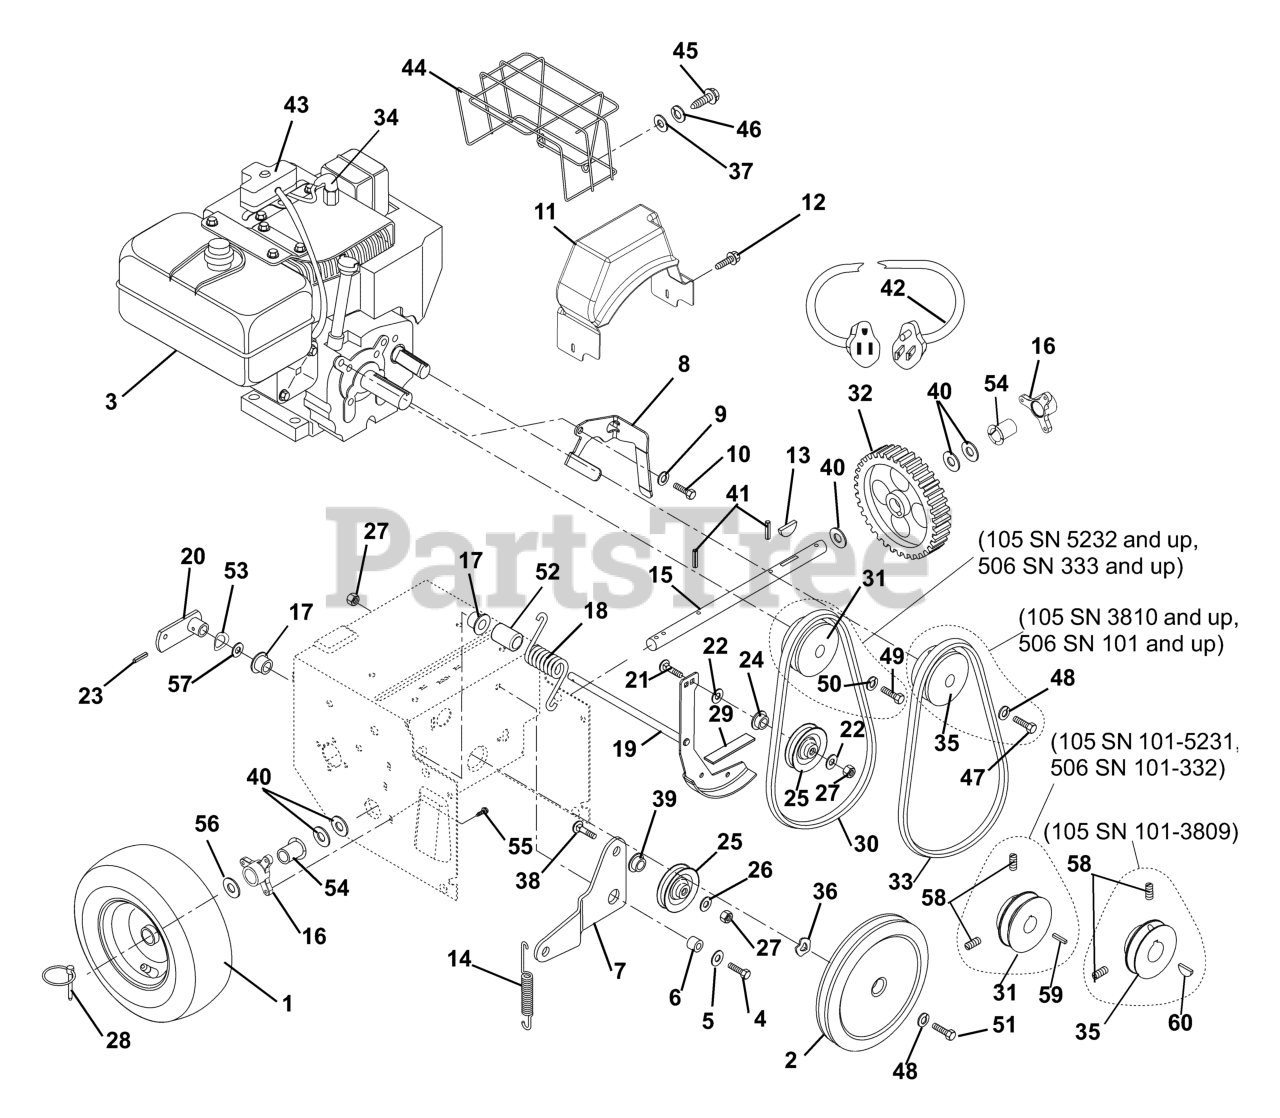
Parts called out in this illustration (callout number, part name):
1	WHEEL 5.00 X 6.00
2	PULLEY, 3L W/HUB, .625 X 6.5
3	ENGINE, 8.5HP TEC LHSA318 120V
4	@BLT-HEX .31-18X.75 GR5 YWZC
5	@WSHR-FL-STL.38X.875X.083 YWZC
6	SPACER BUSHING .5 X .32 X .163
7	IDLER ARM
8	BELT FINGER
9	WSHR-LK .312X.097 HVY YWZC
10	BLT-HEX .31-24X.75 YWZC GR5
11	COVER, BELT, HYBRID
12	@SCR-TAP .25-20X.37 HWH YWZ TR
13	KEY-WDRF .25X.750X.313 SAE91
14	SG-TENS .047X.44X3.37 WLD 1.47
15	AXLE SHAFT, 932 DELUXE (8526)
16	BUSHING, RAKE SHAFT .75"
17	BSHG-FLG .500X.625X.500X.750
18	SG-TORS
19	BRAKE ARM W/PAD
20	LEVER, CLUTCH
21	@BLT-RDHDSQNK .31-18X1.25 G5YZ
22	@WSHR-FL-STL.38X.875X.083 YWZC
23	PIN-ROLL .156X.88
24	SPCR, BRG .315X.50X.688X.281
25	IDLER
26	@WSHR-FL-STL.38X.875X.083 YWZC
27	@NUT-LK-CTR .31-18 YWZC
28	PIN-LOK .31X1.75
30	V-BELT, HA-RAW EDGE
31	SHEAVE, ENGINE LHSA318
32	SPUR GEAR, FELLOWS 35T .750 ID
33	V-BELT, 3L-RAW EDGE
34	PLUG, SPARK
35	SHEAVE, CAMSHAFT LHSA318
36	WSHR-WAVE .69X.84X.011
37	@WSHR-FL-STL.219X.50X.049 YWZC
38	BLT-RDHDSQNK .31-18X1.0 SHTYZ
39	BSHG, FLG .325X.499X.26X.88
40	WSHR-FL-STL.754X1.125X.062YWZC
41	PIN-ROLL .156X1.00
42	CORD, ELECTRIC START CORD 120V
43	120 V STARTER KIT- 8 TO 11.5HP
44	MUFFLER GUARD 8 & 10 HP
45	SCR-TAP 10-16X.75 YWZC
46	@WSHR-LK #10X.047 REG YWZC
47	BLT-HEX .25-28X1.0 GR5 YZ EP80
48	WSHR-LK .250X.077 HVY YWZC
49	BLT-HEX .38-24X1.0 GR5 YZ EP80
50	@WSHR-LK .38X.094 REG YWZC
51	BLT-HEX .25-28X.75 GR5 YZ EP80
52	BSHG-SLV .515X.875X1.50
53	WSHR-WAVE .50X.75X.015 .13FRHT
54	BSHG-FLG, SPLIT NYLINER .75"HP
55	SCR-TAP, .25-20X.50 TR YZ W/VT
56	WSHR-FL-STL .755X1.25X.125 YZ
57	WSHR-FL-STL .505X1.00X.062YWZC
58	SCR-SET .31-18X.38 SKHCUPDL
59	KEY-STR .25X1.75X.25
60	KEY-WDRF .125X.625X.250 SAE5
